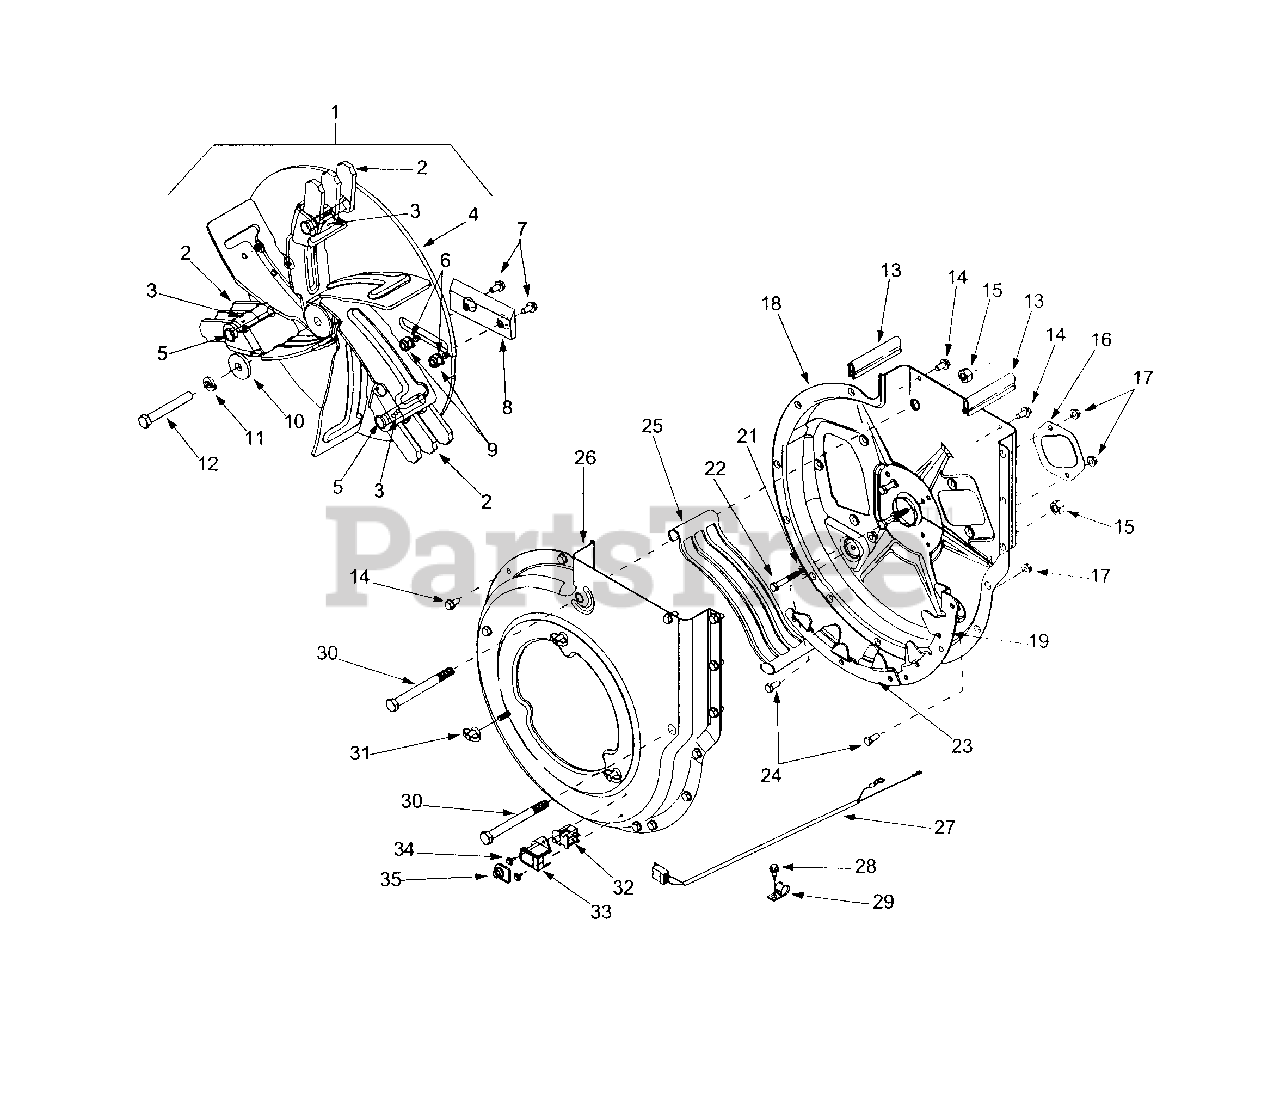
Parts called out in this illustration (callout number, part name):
1	Impeller Ass'y Complete
2	Flail Blade
3	Spiral Pin
4	Impeller Assembly
5	Clevis Pin
6	Lock Washer 5/16
7	Cap Screw 5/16-24 x 1.0
8	Chipper Blade
9	Hex Lock Nut 5/16-24
10	Flat Washer .406 x 1/1/4
11	Lock Washer 3/8
12	Hex Cap Screw 3/8-24 x 2.75
13	Rubber Seal
14	Hex Washer Screw 5/16-18
15	Hex Lock Nut 1/2-13
17	Hex Flange Lock Nut 5/16-18
19	Upper Shredder Blade
21	Lock Washer 5/16
22	Hex Cap Screw 5/16-18 x 2
23	Flail Housing Blade
24	Hex Cap Screw 5/16-18 x .75
25	Discharge Screen
27	Wire Harness
28	Hex Washer Screw 1/4-14
29	Clamp
30	Hex Cap Screw 1/2-13 x 5.0
31	Knob 5/16-18
32	Switch
33	Safety Switch Mounting Cover
34	Hex Washer Screw
35	Switch Cover
